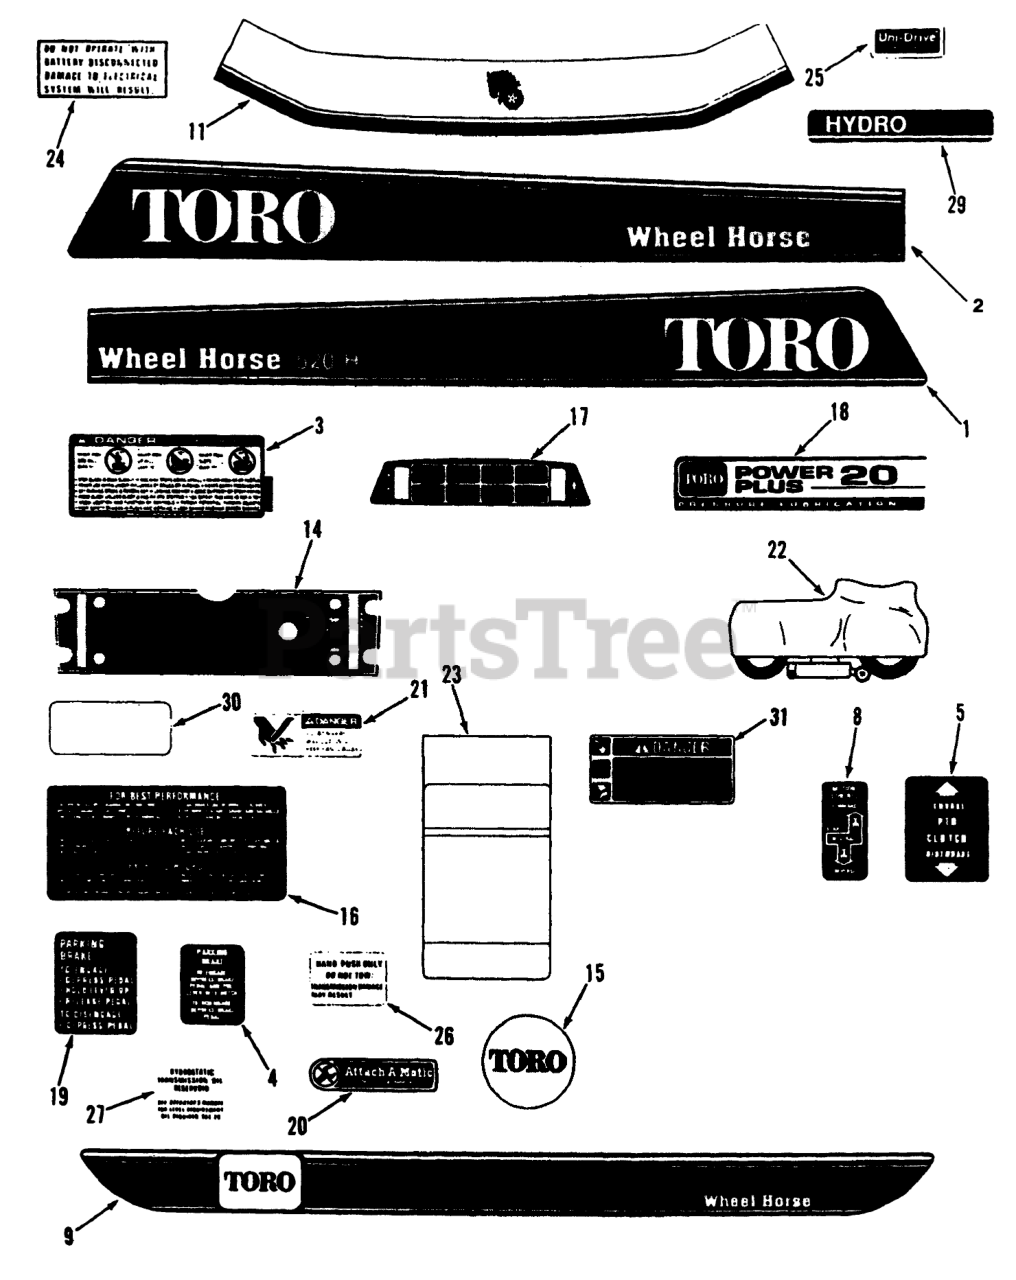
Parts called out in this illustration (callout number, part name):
1	DECAL HOOD 520H, RH
2	DECAL HOOD 520H, LH
3	DECAL-DANGER
4	DECAL-PARKING BRAKE
5	DECAL PTO CLUTCH
8	DECAL-MOTION CONTROL
9	DECAL-FENDER
11	DECAL-FRONT HOOD
14	DECAL-FRONT PANEL
15	NAME-PLATE TORO LOGO
16	DECAL-REAR HOOD
17	DECAL-IND LIGHTS
18	DECAL-PWR PLUS 20 PL
19	DECAL-PARKING BRAKE
20	Decal-Attac-O-Matic
21	DECAL-DANGER
22	Plastic Cover
23	MAINTENANCE-DECAL
24	DECAL ELECT SYSTEM
25	Decal-Unidrive
26	DECAL-DO NOT TOW
27	Decal-Danger
29	DECAL-MODEL HYDRO
31	DECAL-DANGER
